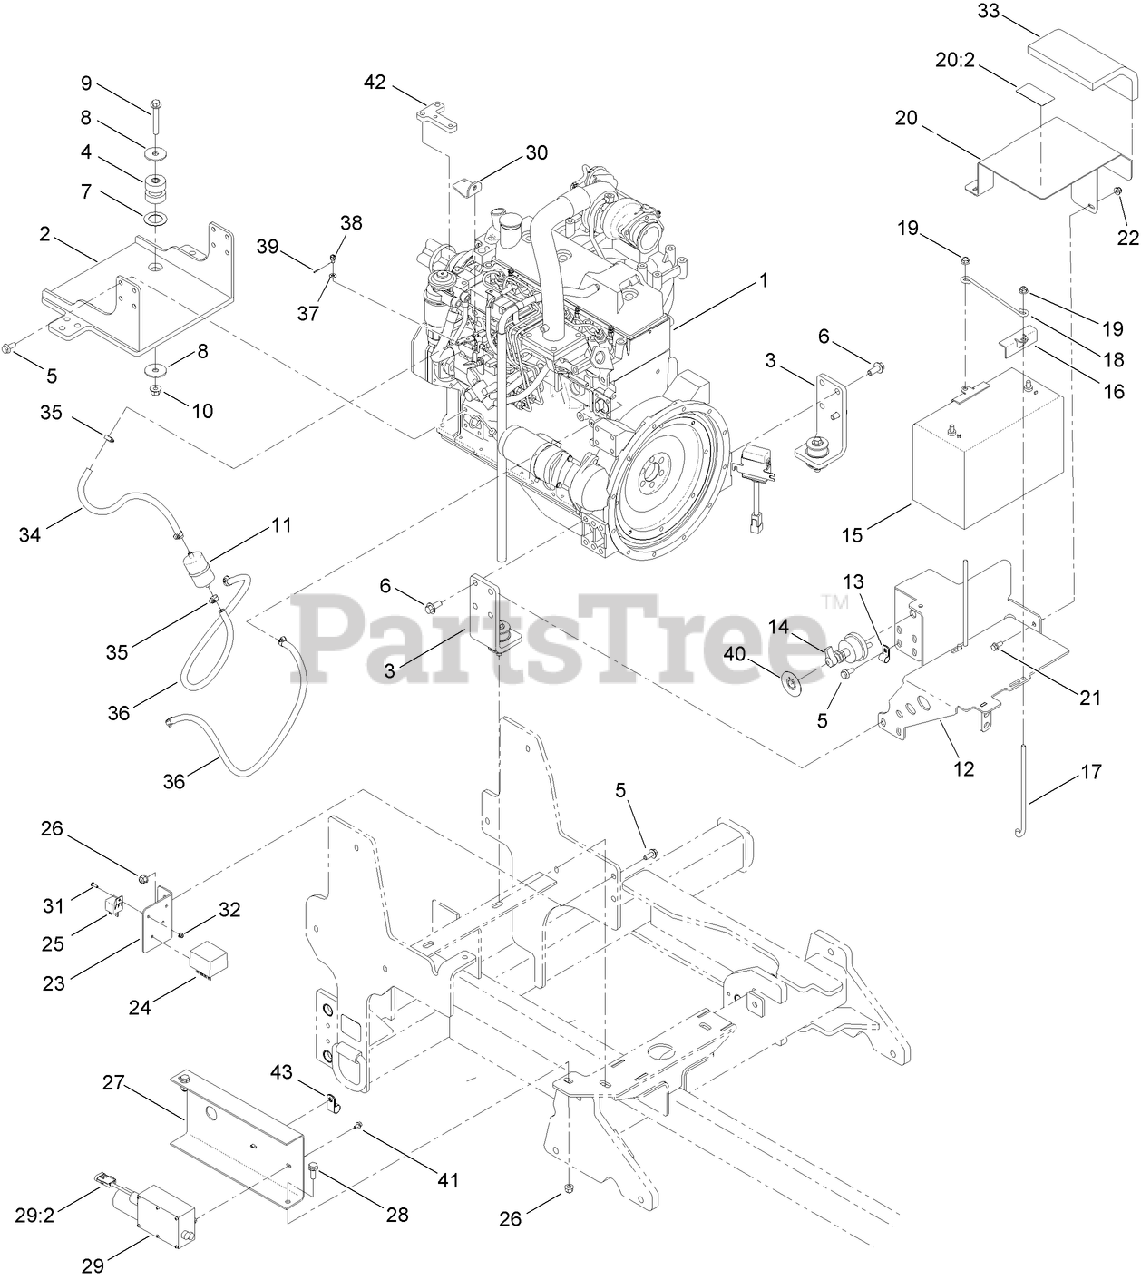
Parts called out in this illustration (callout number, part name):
1	ENGINE ASM
2	MOUNT-ENGINE AND RADIATOR
3	BRACKET-MOUNT, ENGINE
4	ISOLATOR-MOUNTING, UNIVERSAL
5	SCREW-HHF
6	SCREW-HHF
7	SPACER-ISOLATOR
8	WASHER-FLAT
9	SCREW-HHF
10	NUT-LOCK, HHF
11	FILTER-INLINE FUEL
12	BRACKET-MOUNT, BATTERY
13	R-CLAMP
14	SWITCH-BATTERY (1000 AMP)
15	BATTERY (1000CCA, WET)
16	ANGLE-HOLDDOWN, BATTERY
17	BOLT-HOLDDOWN, BATTERY
18	BRACKET-HOLDDOWN, BATTERY
19	NUT-HF, NI
20	BATTERY SHIELD ASM
20:2	DECAL-WARNING, BATTERY
21	SCREW-HHF
22	NUT-LOCK, HHF
23	BRACKET-MOUNTING, RELAY
24	RELAY-CONTROL, ENGINE
25	RELAY-POWER
26	NUT-LOCK, NI
27	BRACKET-THROTTLE
28	SCREW-HHF
29	ACTUATOR-THROTTLE
29:2	CONNECTOR
30	BRACKET-THROTTLE
31	SCREW-HSBH
32	NUT-HF
33	SHIELD-HEAT
34	HOSE-FUEL
35	CLAMP-WORM
36	HOSE-FUEL
37	WASHER-FLAT
38	PIVOT-THROTTLE
39	PIN-COTTER
40	FACEPLATE-BATTERY, ON/OFF
41	SCREW-HHF
42	PLATE-MOUNT, FILTER
43	CLAMP-R
